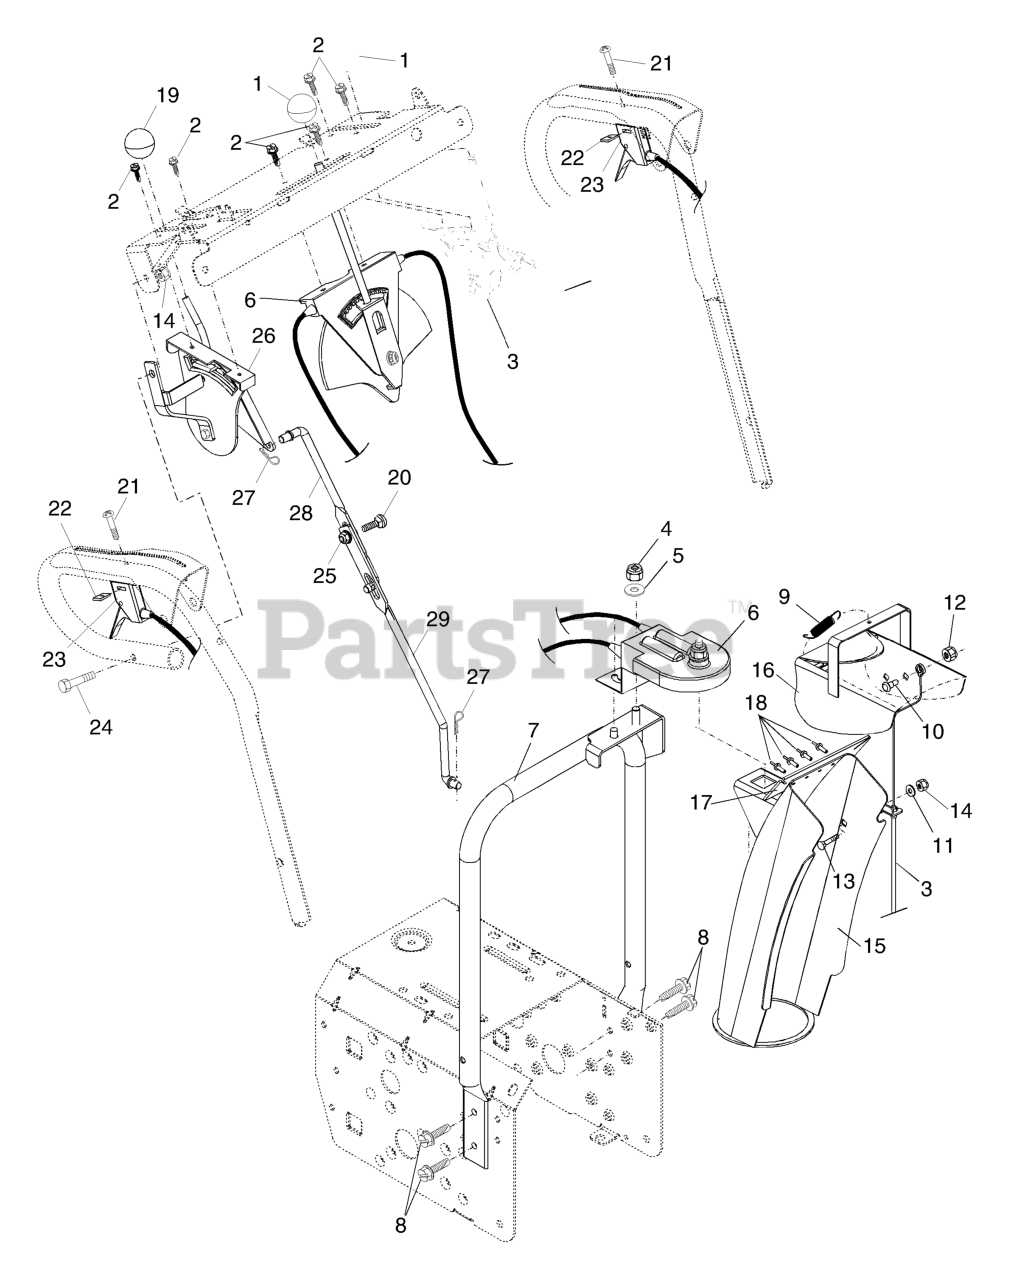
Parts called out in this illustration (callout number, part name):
1	KNOB, LEVER
2	SCREW #10-24 X 5/8
3	CONTROL ASSY, DEFLECTOR
4	NUT
5	WASHER
6	CONTROL ASSY, CHUTE ROTATER
7	SUPPORT CHUTE ROTATER
8	SELF-TAPPING SCREW 5/16-18X3/4
9	SPRING, DEFLECTOR
10	BOLT, SHOULDER
11	WASHER.20X8.5
12	LOCKNUT.NYLOC.1/4-20
13	BOLT
14	NUT.71038.31-18.HEX.NYLOCK
15	CHUTE ASSY
16	DEFLECTOR.WELDMENT.PNT.ORANGE
17	SEAL, DEFLECTOR
18	RIVET BLIND
19	RP KNOB, SPEED CONTROL LEVER
20	BOLT
22	NUT, WELD # 10-24
23	CONTROL ASSY, POWER STEERING
25	NUT.FLANGE.5/16
26	LEVER ASSEMBLY, SPEED CONTROL
27	SPRING RETAINER
28	ROD, UPPER SPEED CONTROL
29	ROD, LOWER SPEED CONTROL
